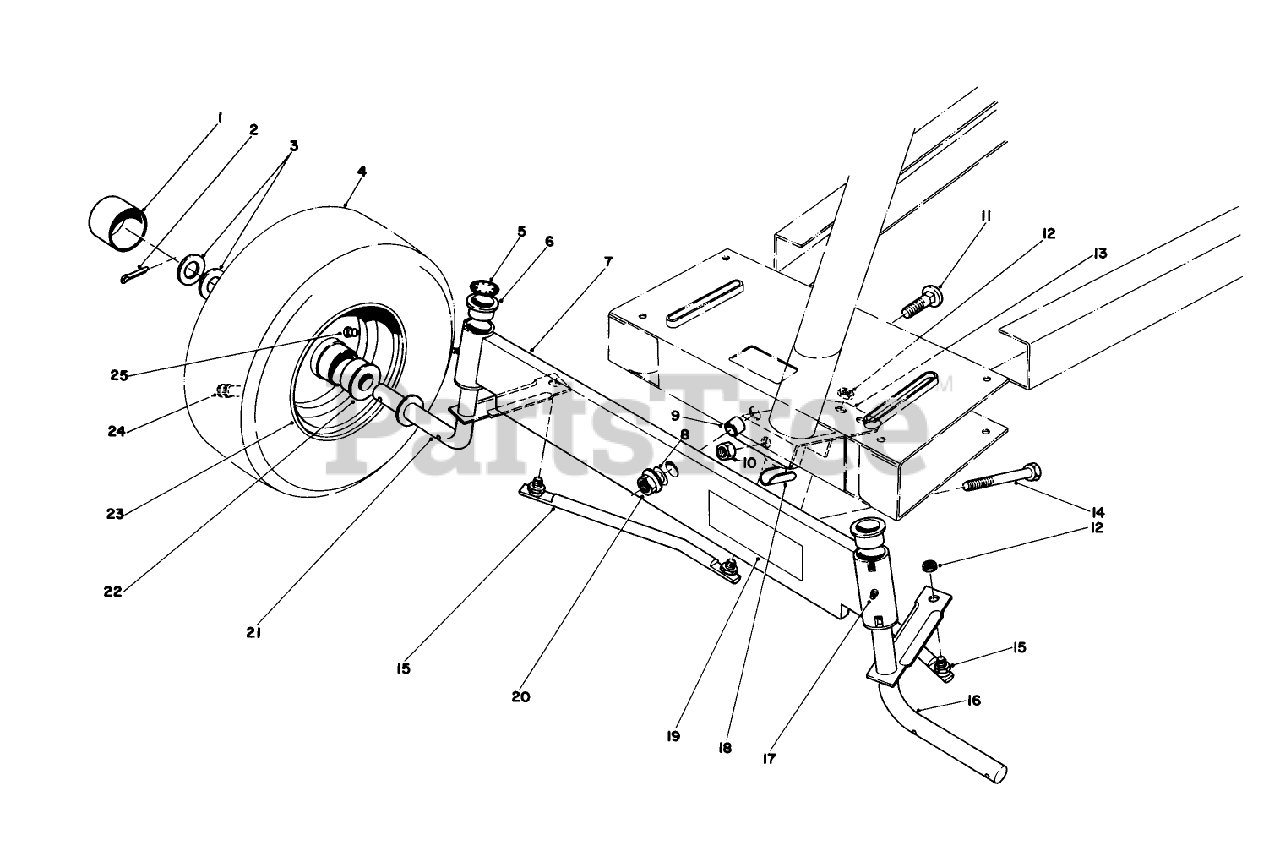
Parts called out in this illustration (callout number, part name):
2	PIN-COTTER
3	WASHER-FLAT
5	RING-RETAINING
8	WASHER-THRUST
10	NUT-LOCK, CONE
11	SCREW-CARR
12	NUT-LOCK, NI
14	SCREW-HH
15	TIE ROD ASM
17	GREASE FITTING
20	NUT-HF
22	BUSHING
25	FITTING-GREASE
